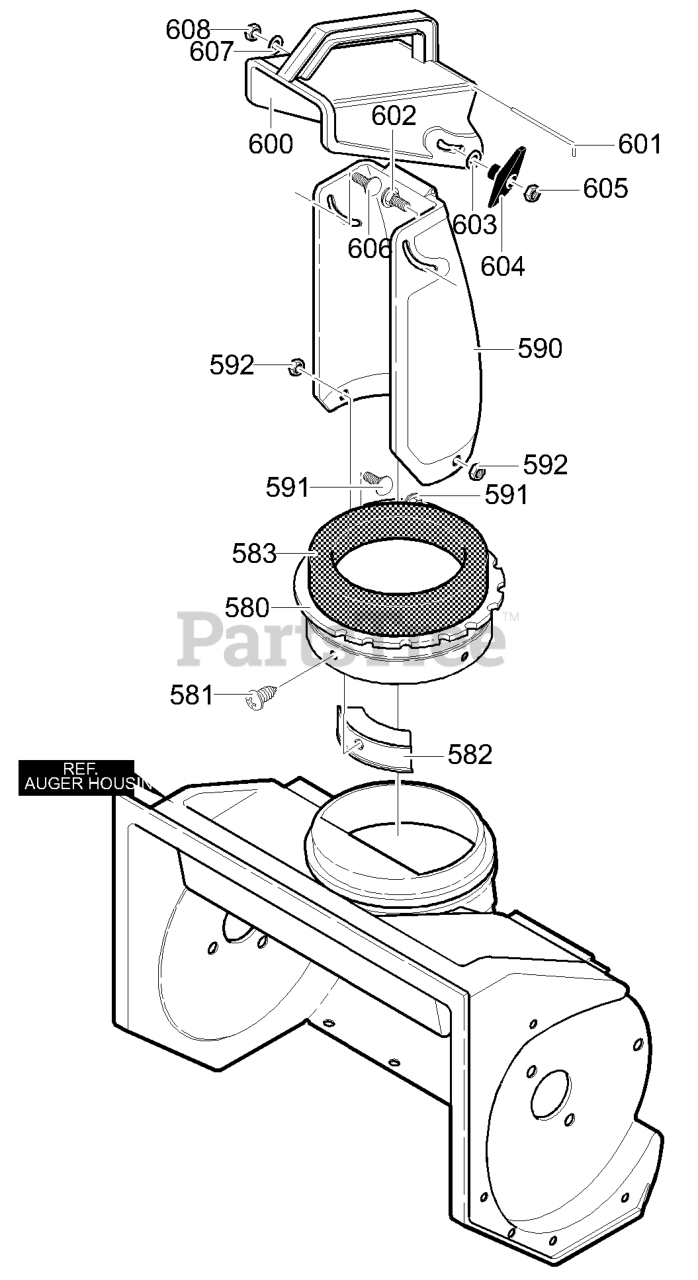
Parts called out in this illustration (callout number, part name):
580	RING, CHUTE
582	GUIDE, CHUTE
583	DONUT, FOAM
590	CHUTE, LOWER
591	SCREW, 1/4-20X .50
592	NUT, CNTRLK 1/4-20
600	CHUTE, UPPER WITH HANDLE
602	BOLT, 5/16-18X1.25
603	WASHER, FLAT
604	T-KNOB
605	NUT, 5/16-18
606	SCREW, 5/16-18 x 0.75 SL
607	WASHER, FLAT
608	NUT, 5/16-18
